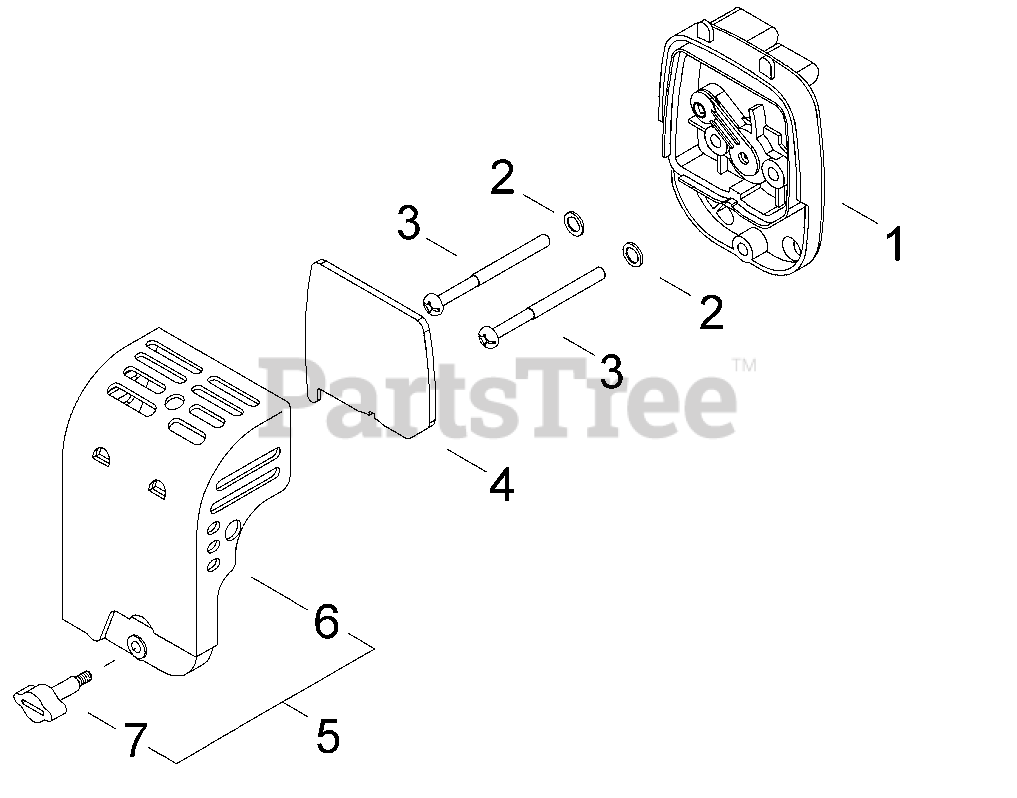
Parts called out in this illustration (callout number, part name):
1	CASE ASSY, AIR FILTER
2	WASHER 5 MM
3	SCREW M5×60
4	FILTER, AIR
5	AIR FILTER COVER ASSY
6	COVER, AIR FILTER
7	THUMBSCREW M5
